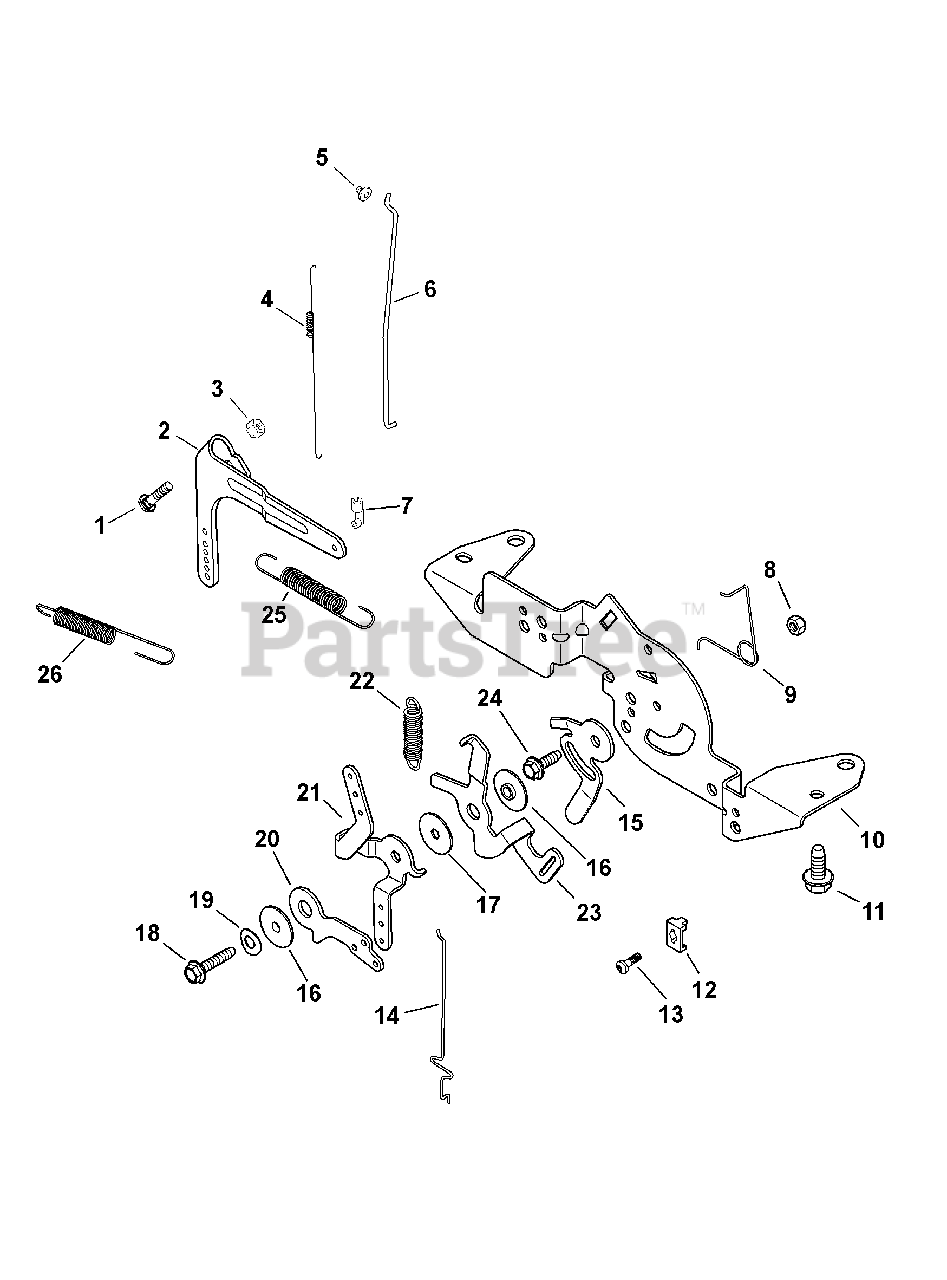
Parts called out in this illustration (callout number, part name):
1	Rd. Hd. Sq. Neck Bolt, M6 x 1.0 x 25
2	Governor Lever
3	Flg. Nut, M6 x 1.0
4	Linkage Spring
5	Linkage Retaining Bushing
6	Throttle Linkage
7	Throttle Linkage Bushing
8	Lock Nut, M5 x .8
9	Choke Return Spring
10	Control Bracket
11	Flg. Thd. Frm. Screw, M6 x 1.0 x 16
12	Cable Clamp
13	Lbd. Thd. Frm. Screw, M5 x 0.8 x 16
14	Choke Linkage
15	Speed Setting Lever
16	Control Assembly Spacer
17	Flat Washer, 5.5MM
18	Thd. Frm. Screw, M5 x 0.8 x 25MM
19	Spring Washer, 1/4"
20	Choke Lever
21	Speed Control Lever
22	Speed Control Spring
23	Governor Spring Lever
24	Flg. Thd. Frm. Screw, M5 x 0.8 x 16
25	Governor Spring
26	Governor Spring
